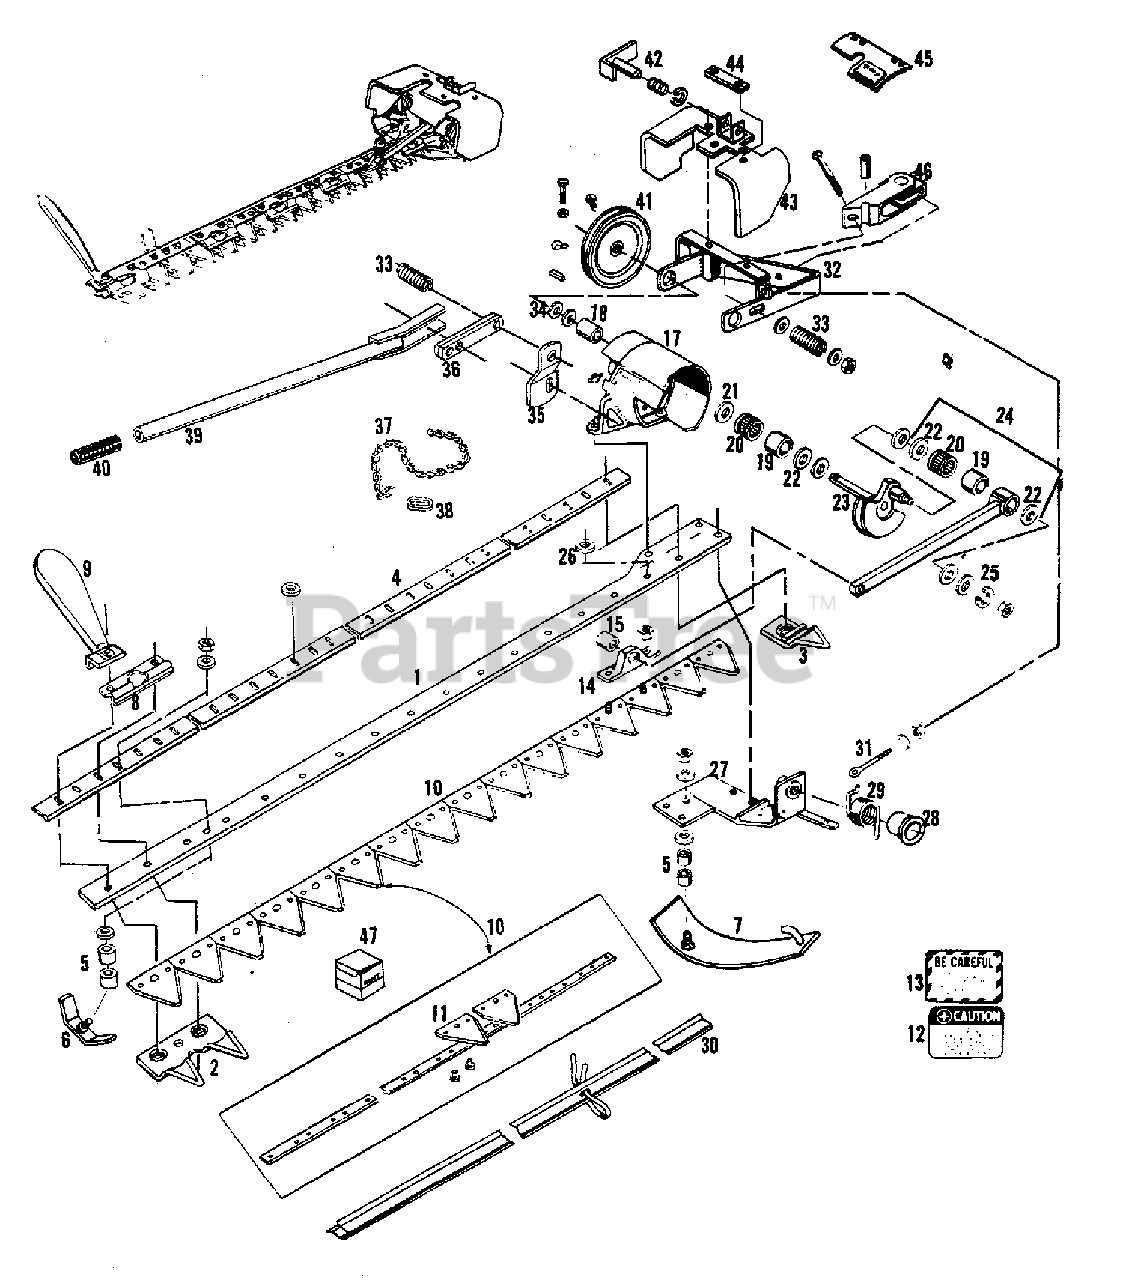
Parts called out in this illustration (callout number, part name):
1	BAR, Sickle
2	FINGER, Shear
2	BOLT, 7/16NC x 1-1/2, Carriage
2	BOLT, 7/16NC x 1-3/4, Carriage
2	LOCKWASHER, 7/16
2	NUT, 7/16NC
3	FINGER, Shear
3	BOLT, 7/16NC x 1-1/2, Carriage
3	LOCKWASHER, 7/16
3	NUT, 7/16NC
4	PLATE, Wear
4	WASHER, 3/8
5	SPACER, 1/2" Long
5	WASHER, 7/16
5	NUT, 1/2NC - Lock
6	SHOE, Outer
7	SHOE, Inner Skid
8	CLIP, Knife
9	DIVIDER, Grass
10	SICKLE ASSEMBLY (Includes KNIVES & RIVETS)
11	KNIFE, Sickle
12	DECAL, Caution
13	DECAL, Be Careful
14	NUT, Cone
15	CAPSCREW, 1/2NC x 1-3/4
15	WASHER, 1/2
15	NUT, 1/2NC - Lock
15	WASHER, 7/16
17	HOUSING, Flywheel
17	FITTING, 1/4NF - Lube (Package Of 10)
17	CAPSCREW, 1/2NC x 1-1/2
17	LOCKWASHER, 1/2
19	BEARING, Outer Race
20	BEARING, Roller
21	WASHER, 1-5/16 x 15/16 x 11 Ga.
22	SEAL, Oil
23	CRANKSHAFT
24	PITMAN ASSEMBLY, Complete
24	FITTING, 1/4NF - Lube (Package Of 10)
25	WASHER, 15/16 x 1-1/2 x .0299
25	WASHER, 1/2
25	LOCKWASHER, 1/2
25	NUT, 1/2NF
26	WASHER, 15/16 x 2 x .0299
27	BRACKET ASSEMBLY, Sickle Mounting
27	CAPSCREW, 1/2NC x 1-1/2
27	LOCKWASHER, 1/2
29	CAPSCREW, 5/8NC x 2-1/4
29	NUT, 5/8NC
30	GUARD, Sickle Bar
30	STRAP, Guard
31	BOLT, Eye
31	WASHER, 3/8
31	NUT, 3/8NC - Lock
32	FRAME ASSEMBLY, Breakaway Pivot
32	BOLT, 3/8NC x 3, Carriage
32	WASHER, 3/8
32	NUT, 3/8NC - Lock
34	WASHER, 49/64 x 1-1/2 x .0598
35	STOP, Vertical
35	CAPSCREW, 3/8NC x 3/4
35	LOCKWASHER, 3/8
35	WASHER, 3/8
36	ARM, Lift
36	BOLT 3/8NC x 3, Carriage
36	WASHER, 3/8
36	NUT, 3/8NC - Lock
37	CHAIN, Transport
38	ANCHOR, Chain
39	HANDLE, Lift
39	CAPSCREW, 1/2NC x 1-1/4
39	NUT, 1/2NC
39	LOCKWASHER, 1/2
40	GRIP, Handle
41	PULLEY, Crankshaft
41	SETSCREW, 5/16NC x 1/2, Square Head, Cup Point
41	CAPSCREW, 1/4NC x 1-3/4
41	NUT, 1/4NC - Lock
41	KEY, 3/16 x 3/16 x 1-1/2
42	PIN ASSEMBLY
42	SPRING, Coupler
42	RING, Snap
43	HOUSING ASSEMBLY
43	CAPSCREW, 3/8NC x 3/4
43	NUT, 3/8NC - Lock
44	BOLT, 1/4NC x 5/8, Carriage
44	NUT, 1/4NC
45	CAPSCREW, 3/8NC x 3/4
45	LOCKWASHER, 3/8
46	LATCH ASSEMBLY
46	CAPSCREW, 3/8NC x 1
46	LOCKWASHER, 3/8
46	NUT, 3/8NC - Lock
47	RIVET, 16 oz. Box
